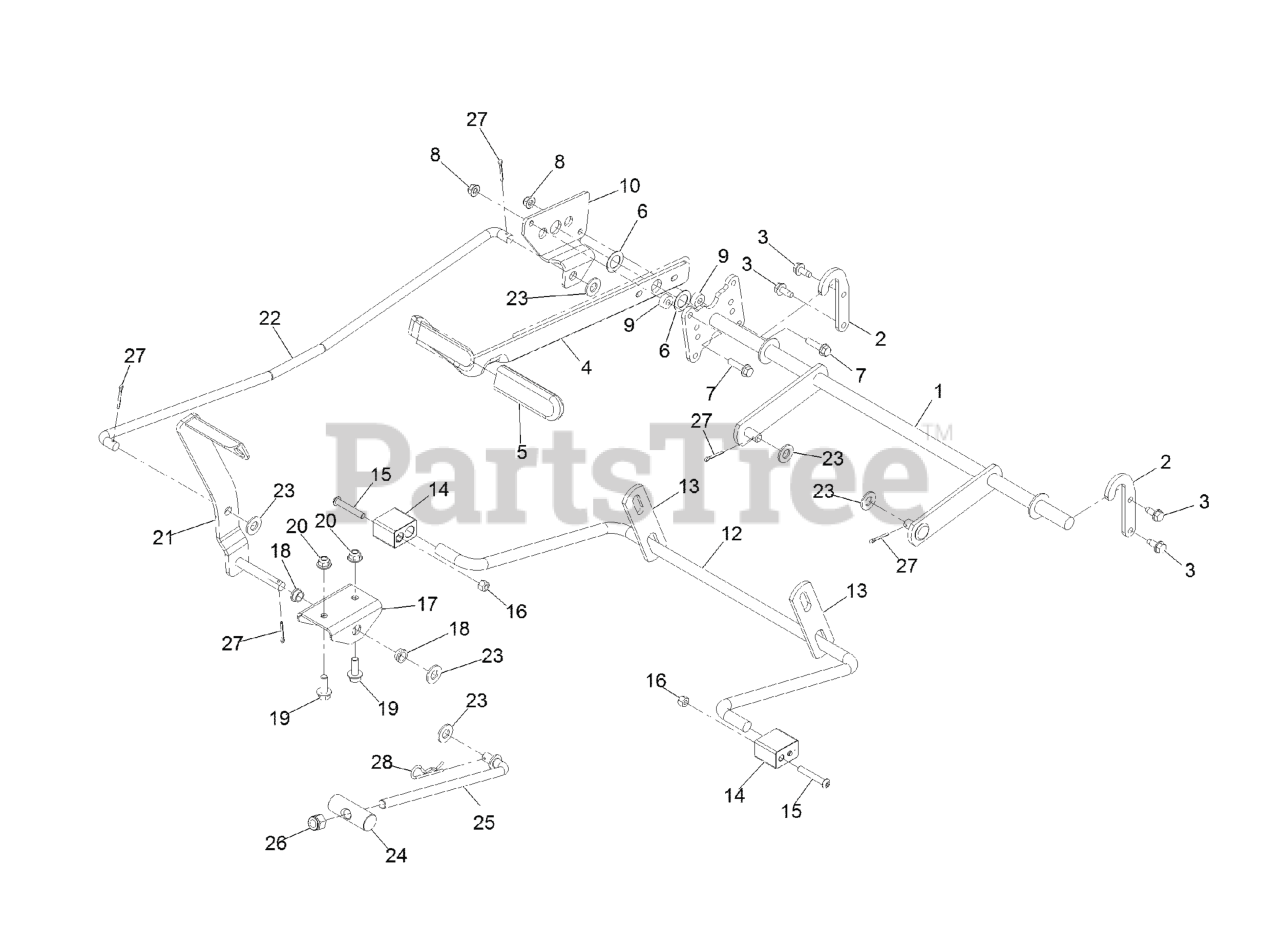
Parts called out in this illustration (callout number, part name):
1	LIFT-DECK, WIDE
2	BRACKET-LIFT
3	Screw-HWH 5/16-18 X 3/4 Tf
4	HANDLE-DECK LIFT
5	GRIP-LEVER
6	WASHER-THRUST
7	SCREW-HHF
8	NUT-HF, NI
10	PLATE-FOOTLIFT
12	ARM-LIFT, REAR (WIDE)
13	LINK-LIFT
14	BLOCK-PIVOT
15	SCREW-HSBH
16	NUT-LOCK, NI
17	BRACKET-FOOTLIFT
18	BUSHING-FLANGE
19	SCREW-HHF 3/8-16 X 1
20	NUT-HF, NI
21	PEDAL ASM
22	ROD-FOOTLIFT
23	WASHER-FLAT
24	PIN-PIVOT
25	ROD-MOUNT, DECK
26	NUT-HEX
27	PIN-COTTER
28	PIN-COTTER
